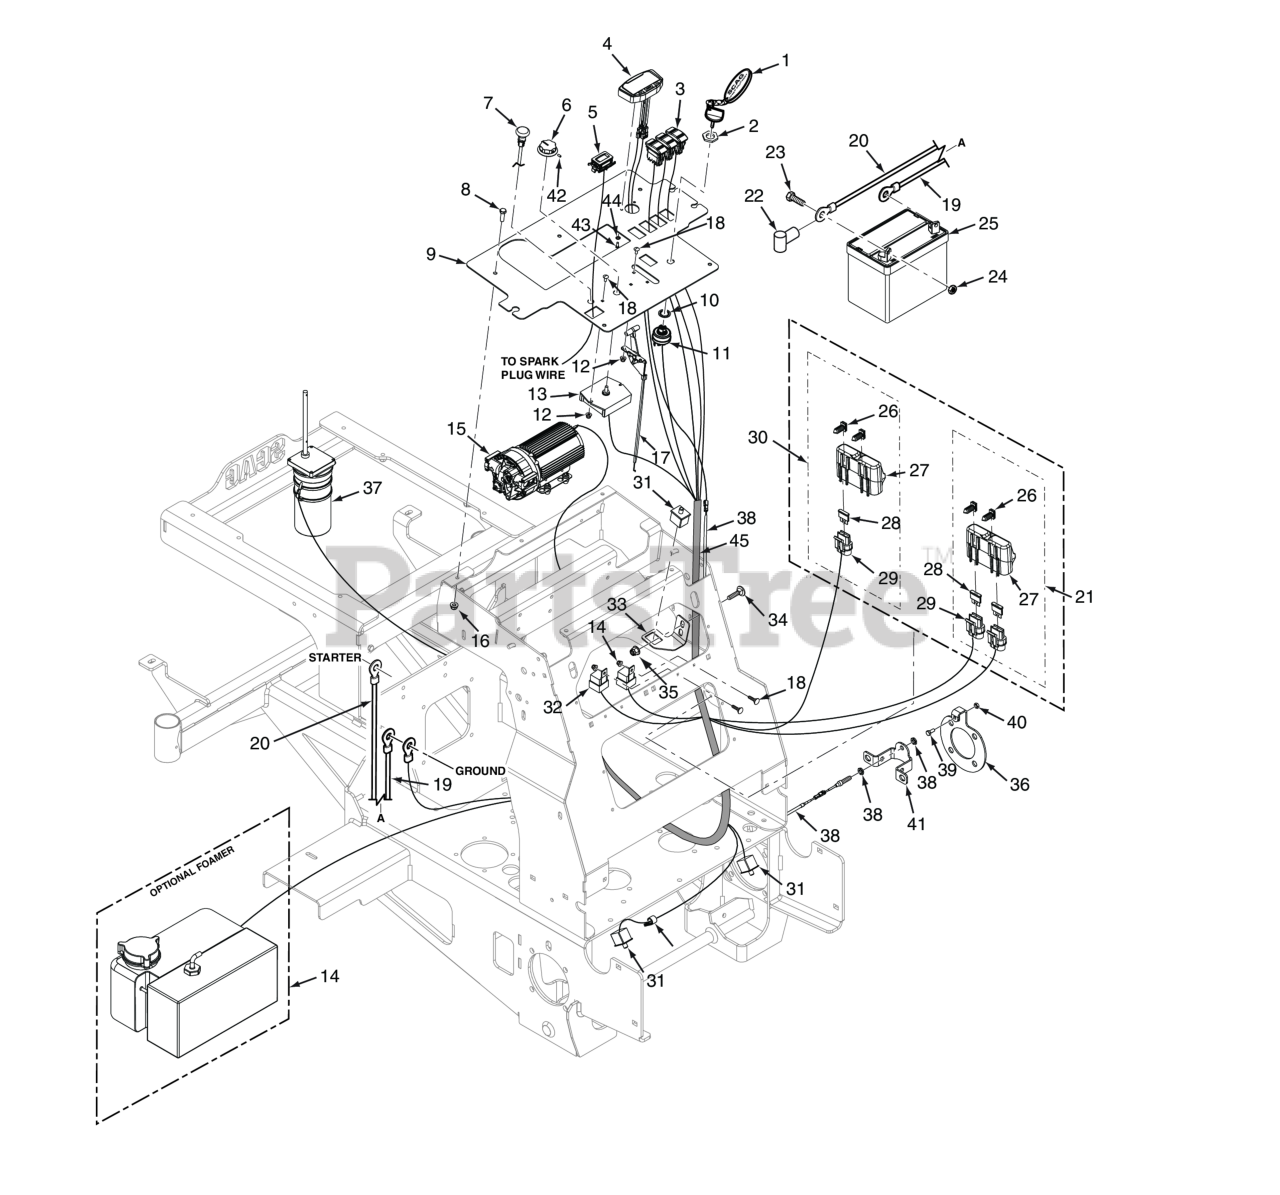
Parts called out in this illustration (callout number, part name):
1	Key, Assembly w/Fob
2	Nut, 5/8-32 Special
3	Switch, Rocker - Lighted
4	Display, Trail Tech
5	Hour Meter, Inductive
6	Knob (Incl #38)
7	Choke Control (excludes EFI models)
8	Bolt, Hex 5/16" - .375 x 1.00- Stainless Steel
9	Instrument Panel w/ Decal
10	LOCK WASHER, 5/8" INTERNAL TOOTH
11	KEY SWITCH(INCLUDES MOUNTING HARDWARE)
12	Locknut, #10 - 32 Elastic Stop - Stainless Steel
13	Motor Controller
14	Foamer Accessory (optional)
15	Pump, 12V Electric
16	Locknut, 5/16-18 Flg. Elastic Stop - Stainless Steel
17	Throttle Control, SVR
18	Bolt, Carriage #10 - 32 x .50 - Stainless Steel
19	Battery Cable, 31-1/2" Black (25KA, 26DFI, 31DFI) - Kawasaki
20	Battery Cable, Red
21	Double Fuse Assy.
22	RUBBER BOOT
23	BOLT, HEX HEAD, 1/4-20 X 3/4 GR.5
24	Nut, 1/4 - 20 Hex
25	Battery, 350 CCA (not available through Scag)
26	Clip, Fuse Holder
27	Cover, Sealed Double
28	FUSE, 20 AMP BLADE TYPE AUTOMOTIVE
29	Fuse Holder Assembly
30	Double Fuse Assy.
31	Switch, Double Pole - Plunger
32	Relay, 12V 40 AMP Standard
33	Mounting Bracket, Brake Switch
34	Bolt, Carriage 5/16 - 18 x 1" - - Stainless Steel
35	Locknut, 5/16-18 Flg. Elastic Stop - Stainless Steel
36	Plate, Hub Magnet Holder
37	Gear Motor, Electric
38	Wire Harness, Display
39	Bolt, Magnetic
40	Nut, M6 x 1.00
41	Plate, Speed Sensor
42	Set Screw, #8 - 32 x .375
43	Bolt, Hex Head M4-.7 x 10
44	Lockwasher, M4-1.1 x 7.6 x .8
45	Wire Harness, STS
